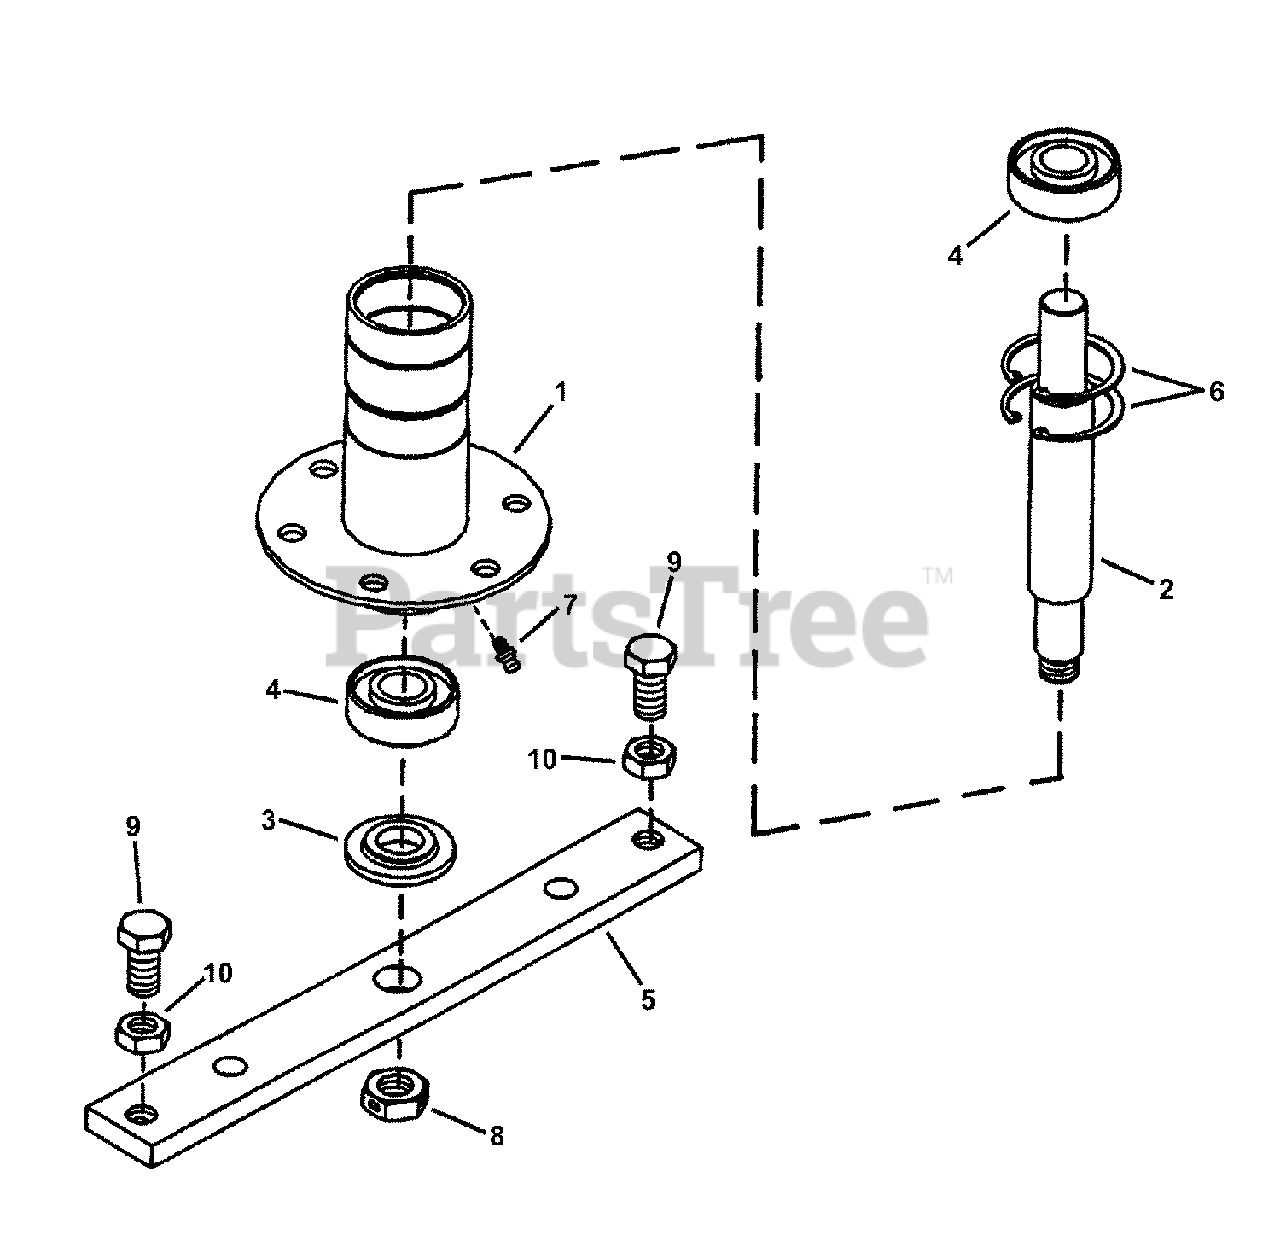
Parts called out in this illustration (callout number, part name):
1	WELDMENT, Spindle Housing
2	SHAFT, Spindle (7.54" long)
3	WASHER, Spindle
4	BALL BEARING, 3/4" I.D.
5	HOLDER, Blade
6	RING, 1-3/4" External Retaining Ring
7	FITTING, Lube, Press-In (for .187 dia. Hole)
8	NUT, 5/8-18 Hex Center Lock Jam, GR5 or B
9	SCREW, 1/2-20 x 1" Hex Head Cap
10	NUT, 1/2-20 Hex GR5 or B
